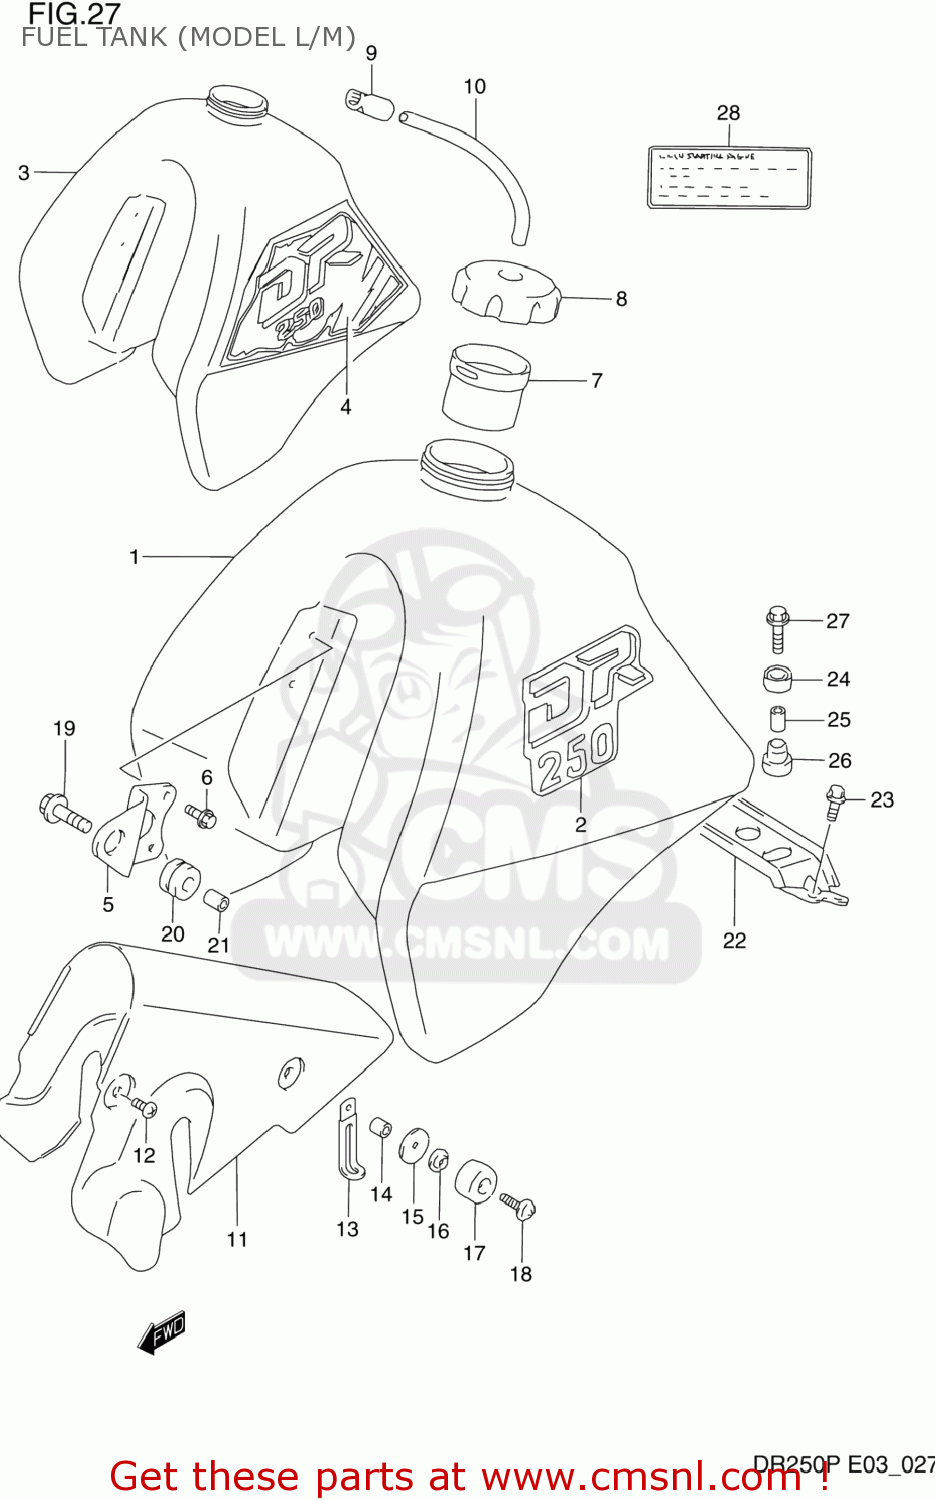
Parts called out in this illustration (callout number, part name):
1	TANK ASSEMBLY,FUEL
2	EMBLEM,FUEL TANK
3	TANK ASSEMBLY,FUEL
4	TAPE SET,FUEL TANK
5	BRACKET,FUEL TANK,FRONT
6	BOLT
7	TUBE,FILLER INLET
8	CAP ASSY,FUEL TANK
9	CLAMP,FUEL TANK BREATHER HOSE
10	HOSE
11	HEAT SHIELD,FUEL TANK
12	SCREW
13	CLAMP
14	SPACER(6.1X14X7.2)
15	WASHER (6.5X26X2.3)
16	WASHER
17	CUSHION
18	SCREW
19	BOLT(8X25)
20	CUSHION
21	SPACER (8.8X12X12.5)
22	BRACKET,FUEL TANK RR
23	BOLT
24	CUSHION
25	SPACER
26	CUSHION
27	BOLT
28	LABEL,STARTING CAUTION
